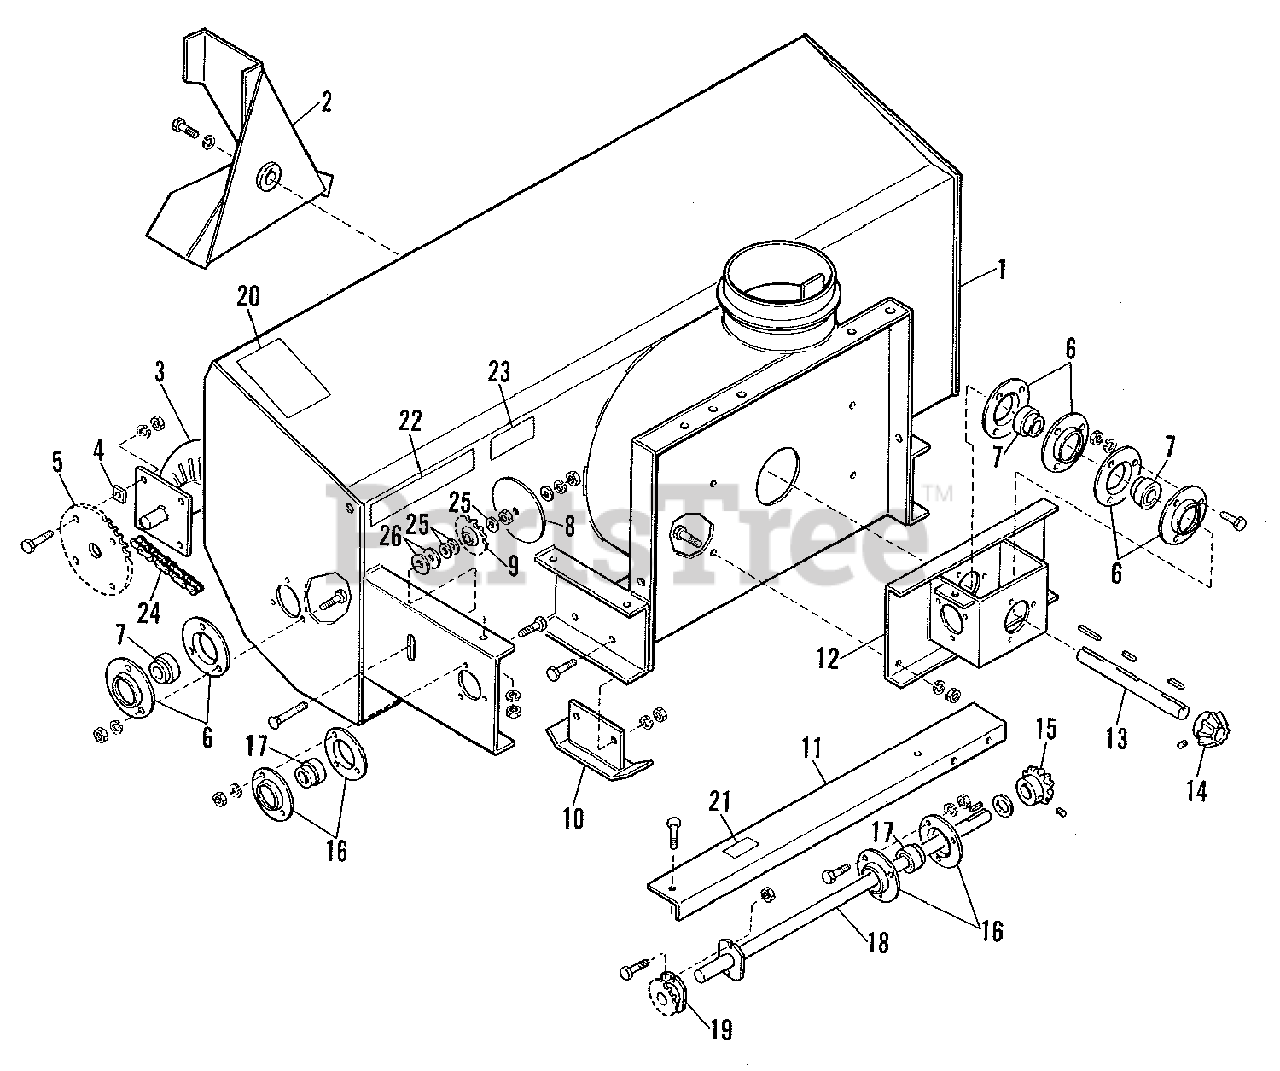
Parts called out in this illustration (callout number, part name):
1	BODY ASSEMBLY
2	ROTOR ASSEMBLY
2	CAPSCREW, 1/2NC x 1
2	LOCKWASHER, 1/2
3	AUGER ASSEMBLY
5	CAPSCREW, 3/8NC x 1-1/2
5	LOCKWASHER, 3/8
6	FLANGE, Bearing (3-Hole)
6	CAPSCREW, 3/8NC x 1
6	LOCKWASHER, 3/8
7	BEARING, Auger & Rotor Shafts
8	SHIELD, Chain
8	BOLT, Carriage, 1/2NC x 2-3/4
8	WASHER, Plain, 13/16 x 1-1/4 x 10 Ga.
8	WASHER, Plain, 9/16 x 1-3/8 x 12 Ga.
8	LOCKWASHER, 1/2
9	IDLER, Chain
10	CAPSCREW, 1/2NC x 1-1/4
10	WASHER, Plain, 9/16 x 1-3/8 x 12 Ga.
10	NUT, Lock, 1/2NC
11	SHIELD, Cross Shaft
11	CAPSCREW, 5/16NC x 3/4
11	WASHER, Plain, 3/8 x 7/8 x 16 Ga.
11	LOCKWSHER, 5/16
11	NUT, 5/16NC
12	CASE, Gear Assembly
12	CAPSCREW, 3/8NC x 1
12	LOCKWASHER, 3/8
13	SHAFT, Rotor
13	KEY, Square, 1/4 x 1/4 x 3
13	KEY, Square, 1/4 x 1/4 x 1-1/2
14	GEAR, Bevel 1-1/4" Bore (19T)
14	SETSCREW, Hex Socket Knurled Cup Point, 3/8 x 1/2
15	GEAR, Bevel, 7/8" Bore (19T)
16	FLANGE, Bearing (3-Hole)
16	CAPSCREW, 5/16NC x 3/4
16	CAPSCREW, 5/16NC x 1
16	LOCKWASHER, 5/16
16	NUT, 5/16NC
17	BEARING, Cross Shaft
18	SHAFT, Cross
18	KEY, Square, 3/16 x 3/16 x 1
18	BOLT, Shear, 1/4NC x 1
18	NUT, Lock, 1/4NC
19	SPROCKET, Auger Drive
20	DECAL, Caution
21	DECAL, Chain Oil
22	DECAL (Allis-Chalmers)
23	DECAL (64 Model Identification)
24	CHAIN, 5/8 Pitch
24	CHAIN, Bulk, 5/8 Pitch (10ft Roll)
24	CHAIN, Bulk, 5/8 Pitch (50ft. Roll)
24	LINK, Roller
24	LINK, Offset
24	LINK, Connecting
25	BUSHING, Machinery
